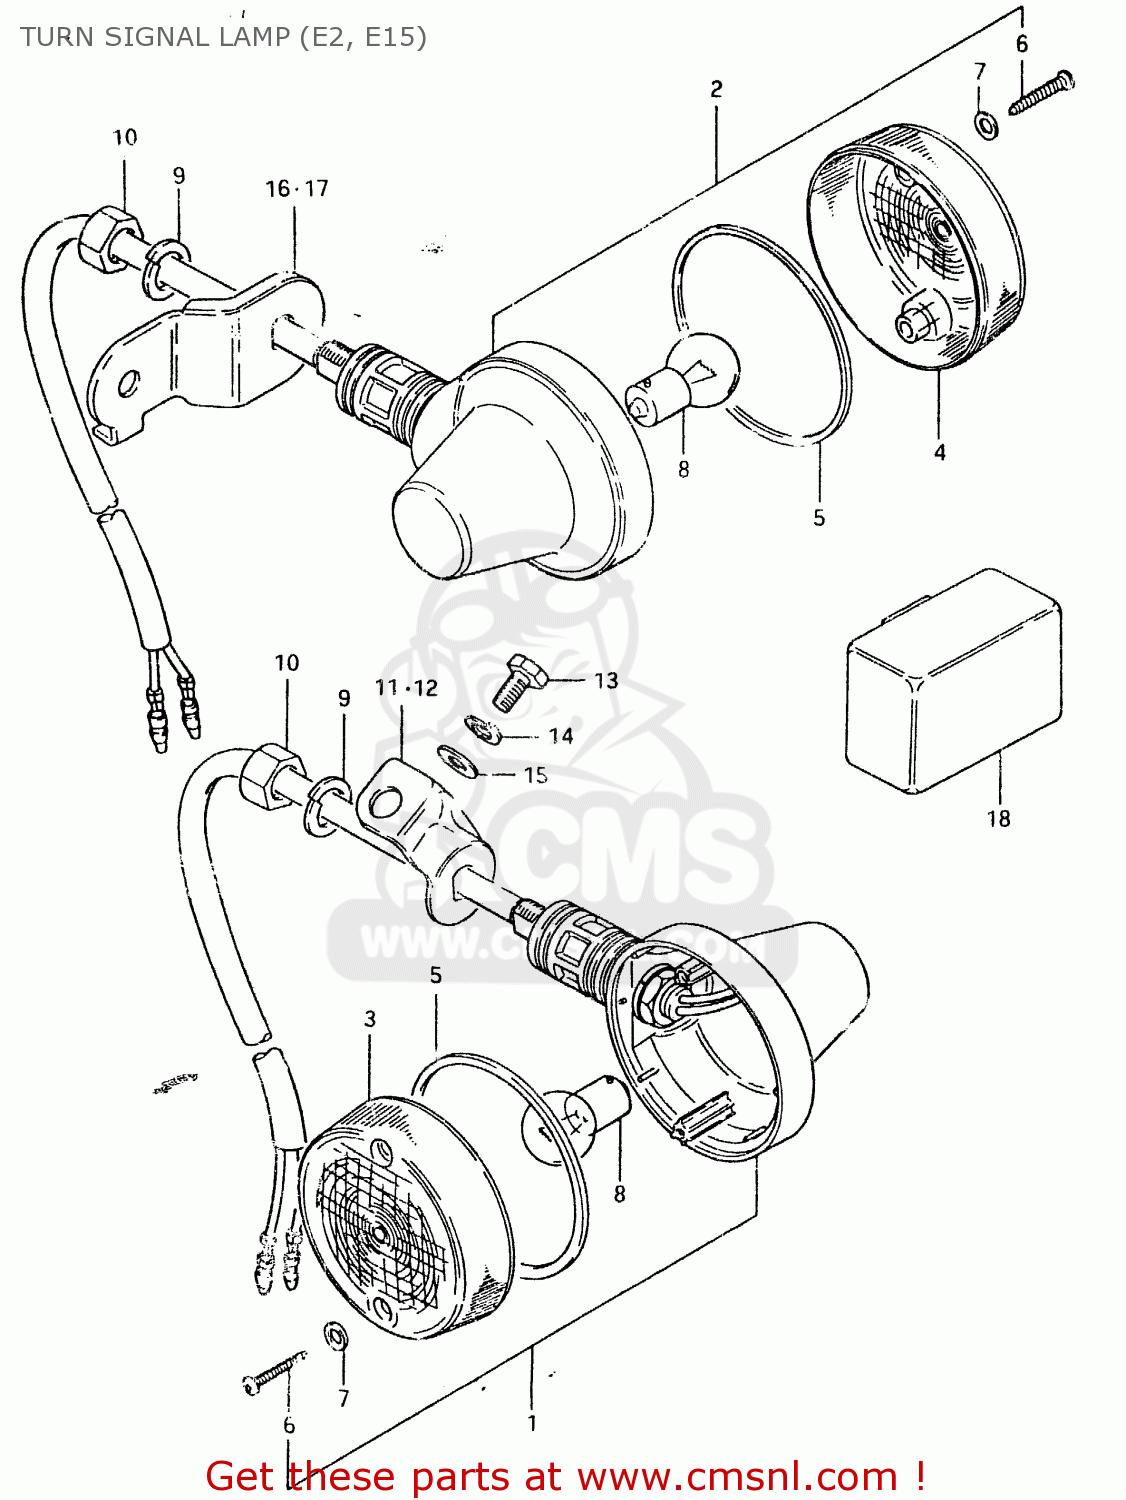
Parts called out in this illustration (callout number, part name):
1	LAMP ASSY,RR TURNSIGNAL
2	LAMP ASSY,RR TURNSIGNAL
3	LENS
4	LENS
5	GASKET (NAS)
6	SCREW TAPP.
7	GASKET (NAS)
8	BULB (6V,18W)
9	WASHER,LOCK 12
10	NUT
11	BRACKET,TURNSIGNAL LAMP,R
12	BRACKET,TURNSIGNAL LAMP,L
13	BOLT
14	LOCK WASHER
15	WASHER
16	BRACKET,REAR TURN SIGNAL
17	BRACKET,REAR TURN SIGNAL
18	RELAY,TURN SIGNAL
